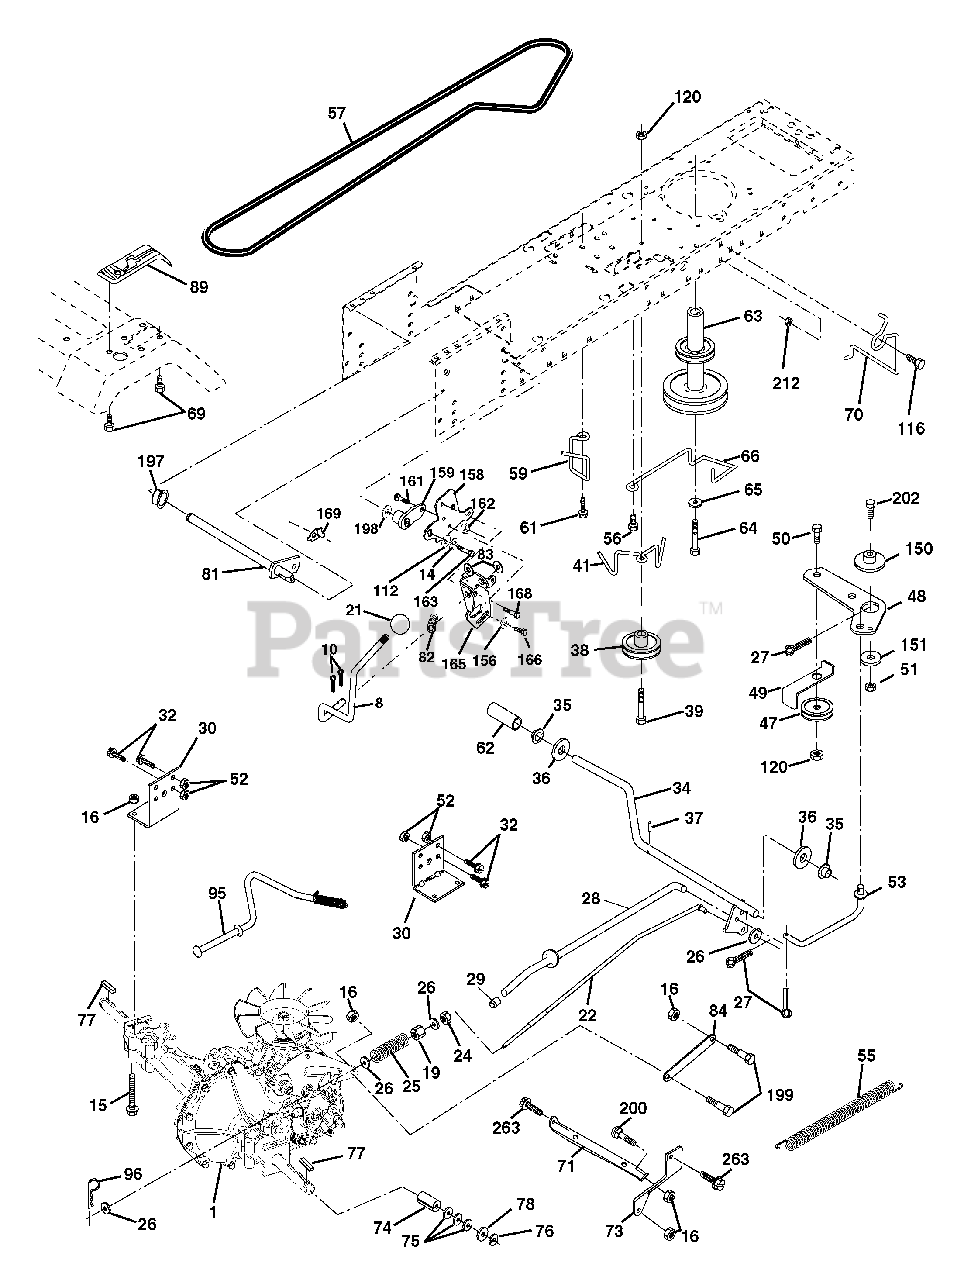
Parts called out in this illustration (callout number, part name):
8	Rod Shift
10	Pin Cotter 1/8 x 1 CAD
14	Washer Lock Hvy Helical
15	Bolt, Hex FLGHD 5/16-18 Gr. 5
16	Nut Lock Hex W/Ins 5/16-18 unc
19	Nut Lock Hex W/Wsh 3/8-16 unc
21	Knob
22	Rod, Brake Hydro
24	Nut
25	Spring, Brake Rod
26	Washer
27	Pin Cotter 1/8 x 3/4 CAD.
28	Rod, Parking Brake
29	Cap, Parking Brake
30	Bracket, Transaxle
32	Bolt Hex Hd 5/16-18 unc x 3/4
34	Shaft, Foot Pedal
35	Bearing, Nylon
36	Washer
37	Pin, Roll
38	Pulley, Composite
39	Bolt Rdhd 3/8-16 unc x 2-3/4 Gr. 5
41	Keeper, Belt Idler
47	Pulley, Idler, V-Groove
48	Bellcrank Clutch Grnd Drv STL
49	Retainer, Belt
50	Bolt Carr Sh 3/8-16 x 1-1/2 Gr. 5
51	Nut Crownlock 3/8-16 unc
52	Nut Crownlock 5/16-18 unc
53	Link, Clutch
55	Spring, Return, Clutch
56	Screw 3/8-16 x 1-1/4
57	V-Belt, Ground Drive
59	Keeper, Center Span
61	Screw 3/8-16 x .875
62	Cover, Pedal
63	Pulley, Engine
64	Bolt Hex 7/16-20 x 4 x Gr. 5-1.5 Thr
65	Washer
66	Keeper Belt Engine
69	Screw Hex Wsh Hi-Lo 1/4-1/2 unc
70	Guide Belt
71	Strap Torque Lh Hydro
73	Strap Torque Rh Hydro
74	Spacer, Axle
75	Washer 25/32 x 1-1/4 x 16 Ga.
76	E-Ring
77	Key, Square
78	Washer 25/32 x 1-5/8 x 16 Ga.
81	Shaft Asm. Cross Hydro
82	Spring Torsion T/A
83	Washer 17/32 x 3/4 x 16 Ga.
84	Link Transaxle
89	Console, Shift
95	Control Asm Bypass Hydro
96	Retainer Spring 1" Zinc/Cad
112	Washer 9/32 x 3/4 x 10 Ga.
116	Bolt RDHD SQNK 3/8-16 unc x 1
120	Nut Lock Flg 3/8-16 unc
150	Spacer Retainer
151	Washer 13/32 x 2 x 10 Ga.
156	Washer Srrted 5/16 ID x 1.125
158	Bracket Shift Mount
159	Hub Shift
161	Bolt Rdhd Sqnk 1/4-20 x 3/4 Gr. 5
162	Nut Crownlock 1/4-20 unc
163	Bolt Hex Fin 1/4-20 unc x 1 Gr. 5
165	Bracket Pivot Lever
166	Screw 5/16-18 x 5/8
168	Bolt Shoulder 5/16-18 x .561
169	Plate Fastening Lt
197	Nyliner Snap-In 5/8" ID
198	Washer Nyl 7/8 ID x .105
199	Bolt Shoulder 5/16-18 unc
200	Bolt Rdhd Sqnk 5/16-18 unc x 1
202	Bolt Carr Sh 3/8-16 x 1-3/4 Gr. 5
212	Nut Hex flange Lock
263	Screw Hexwsh Thdr 3/8-16 x 3/4
